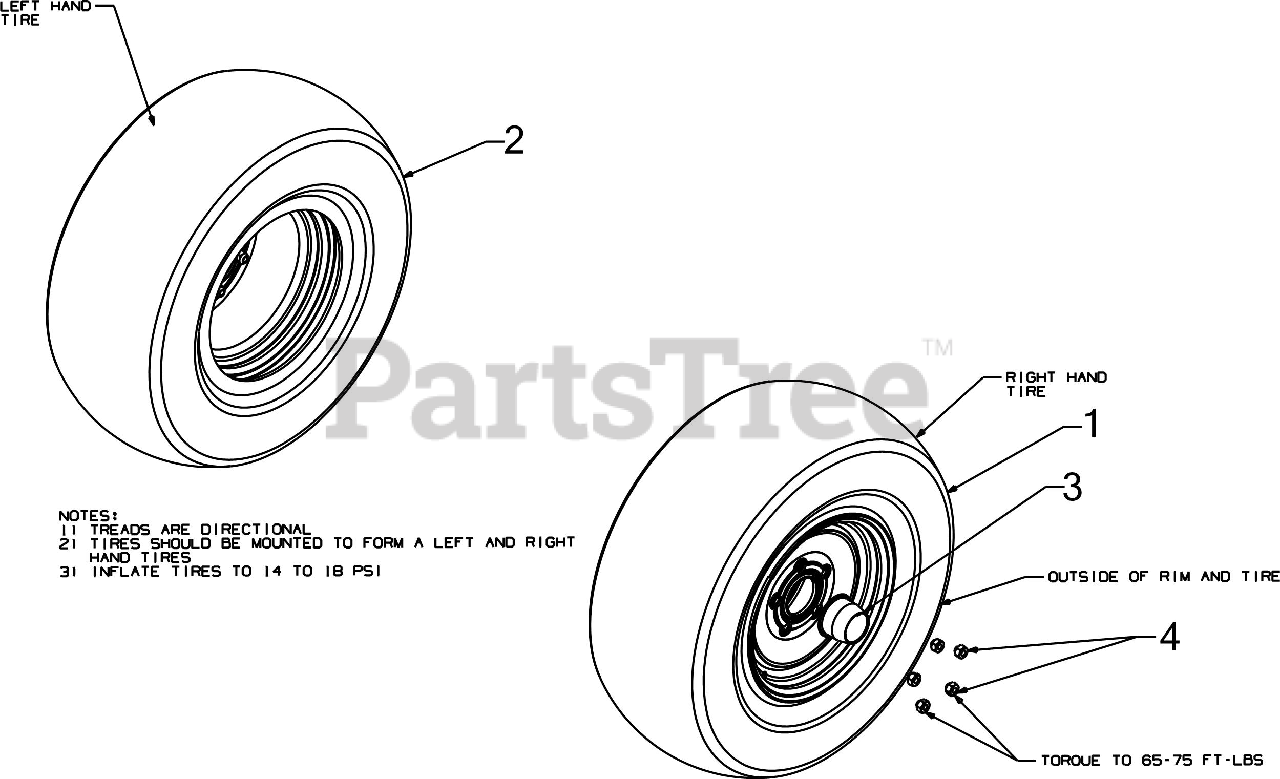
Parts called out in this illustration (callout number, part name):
1	WHEEL ASSEMBLY (26 x 9-12) (RH)
2	WHEEL ASSEMBLY (26 x 9-12) (LH)
4	LUG NUT 7/16-14
